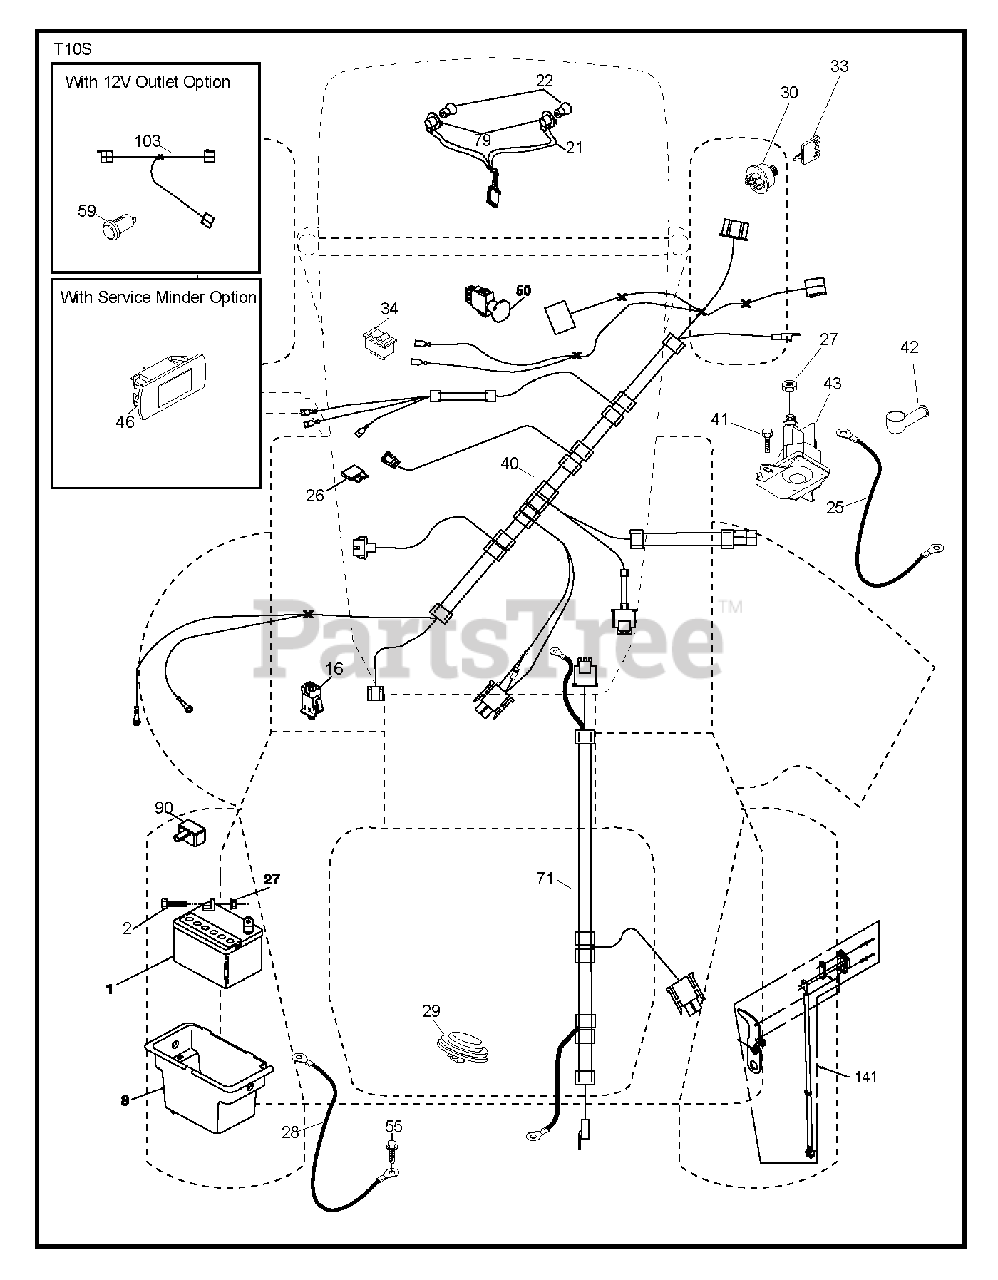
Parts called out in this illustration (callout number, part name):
8	BOX.BATTERY.MNT.REAR.L
16	SWITCH INTERLOOK PUSH-IN
21	HARNESS.LIGHT W/4152J BULBS
22	LIGHTBULB
25	CABLE.STARTER.6GA.BL/RED.14.
26	FUSE 20AMP
27	NUT
28	CABLE.BLACK.18"REAR.BA
29	SWITCH.SEAT.DELTA.OPC.
30	SWITCH.IGN.DELTA.W.LGH.ROS
33	KEY.CHAIN.BLISTER.PACK.GEN.INT
34	SWITCH LT
40	HARNESS.IGN.DASH.HUQ/P
41	SCREW
42	TERMINAL COVER
43	SOLENOID.W/BRASS.PLUNG
46	GUAGE.SRVCMNDR.HRMTR.
50	PTO SWITCH
55	SCREW 5/16"
79	BULB HOLDER ASM.
90	COVER.TERMINAL.BATTERY
141	KIT T2.ROS
